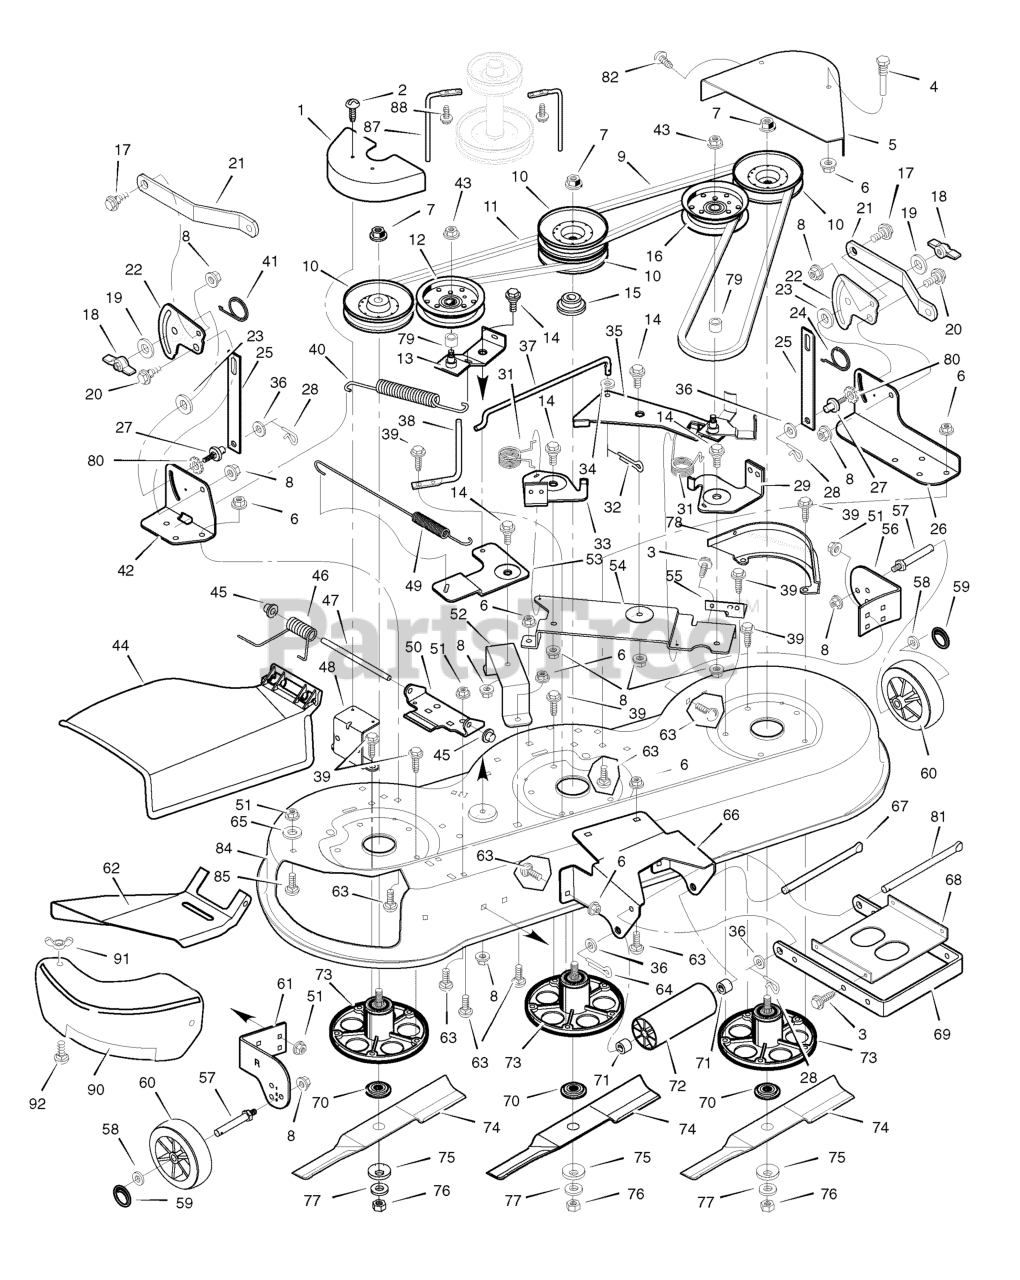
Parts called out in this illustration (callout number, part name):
1	Cover, Right Pulley
2	Screw
4	Guide, Belt
5	Cover, Left Pulley
6	Nut, Hex
7	Nut, Flange
8	Nut, Flange
9	Belt, Primary
11	Belt, Secondary
12	Pulley, Idler
13	Arm, Idler
14	Bolt, Shoulder
15	Spacer, Pulley
16	Pulley, Idler
17	Bolt, Shoulder
20	Bolt, Shoulder
21	Bracket, Rear Suspension
22	Plate, Suspension
23	Pad, Friction
25	Link, Lift
26	Bracket, Left Lift
27	Pin, Hanger
28	Pin, Hair
29	Brake Assembly, Left
32	Pin, Cotter
33	Brake Assembly, Right
34	Washer
35	Idler, Arm
37	Link, Bell Crank
38	Guide, Belt
39	Screw
40	Spring, Extension
41	Spring, Torsion
42	Bracket, Suspension
43	Nut
44	Deflector, Chute
45	Push On Cap
46	Spring, Torsion
47	Rod, Deflector
48	Bracket, Cover
49	Spring, Extension
50	Bracket, Hinge
51	Nut, Flange
52	Bracket, Bell Crank
53	Crank, Bell
54	Plate, Brake Arm
55	Bracket, Brake Plate
56	Bracket, Left Gauge Wheel
57	BOLT, Gauge Wheel
59	Ring, Locking
60	Wheel, Gauge
61	Bracket, Right Gauge Wheel
62	Deflector, Inside
63	Bolt, Carriage
64	Pin, Cotter
66	Bracket, Front Deck
67	Rod, Hanger
69	Bracket, Front Suspension
70	Adapter, Blade
73	Housing, Jackshaft
75	Washer, Belleville
78	Bracket, Pulley Cover
81	Rod, Hanger
84	Housing, Blade
85	Bolt, Carriage
87	Guide, Belt
88	Screw
90	Cover, Mulch
91	Wingnut
92	Bolt, Carriage
